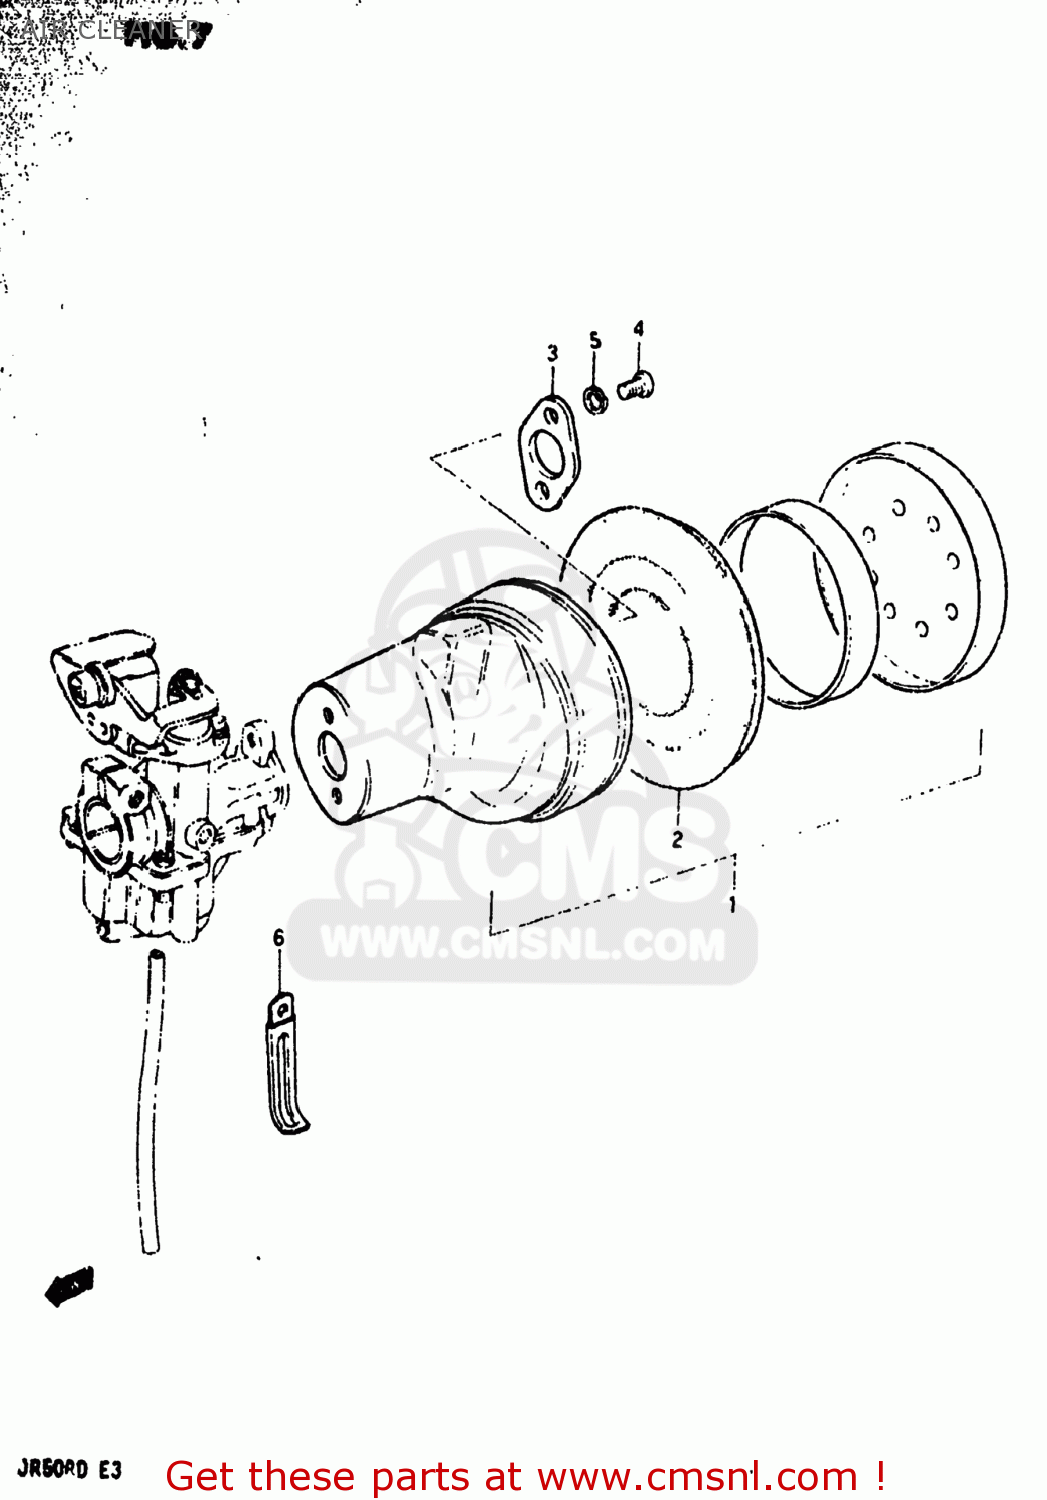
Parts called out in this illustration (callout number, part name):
1	CLEANER ASSY,AIR
2	FILTER,AIR CLEANER
3	PLATE,AIR CLEANER
4	SCREW
5	LOCK WASHER
6	CLAMP L:35
